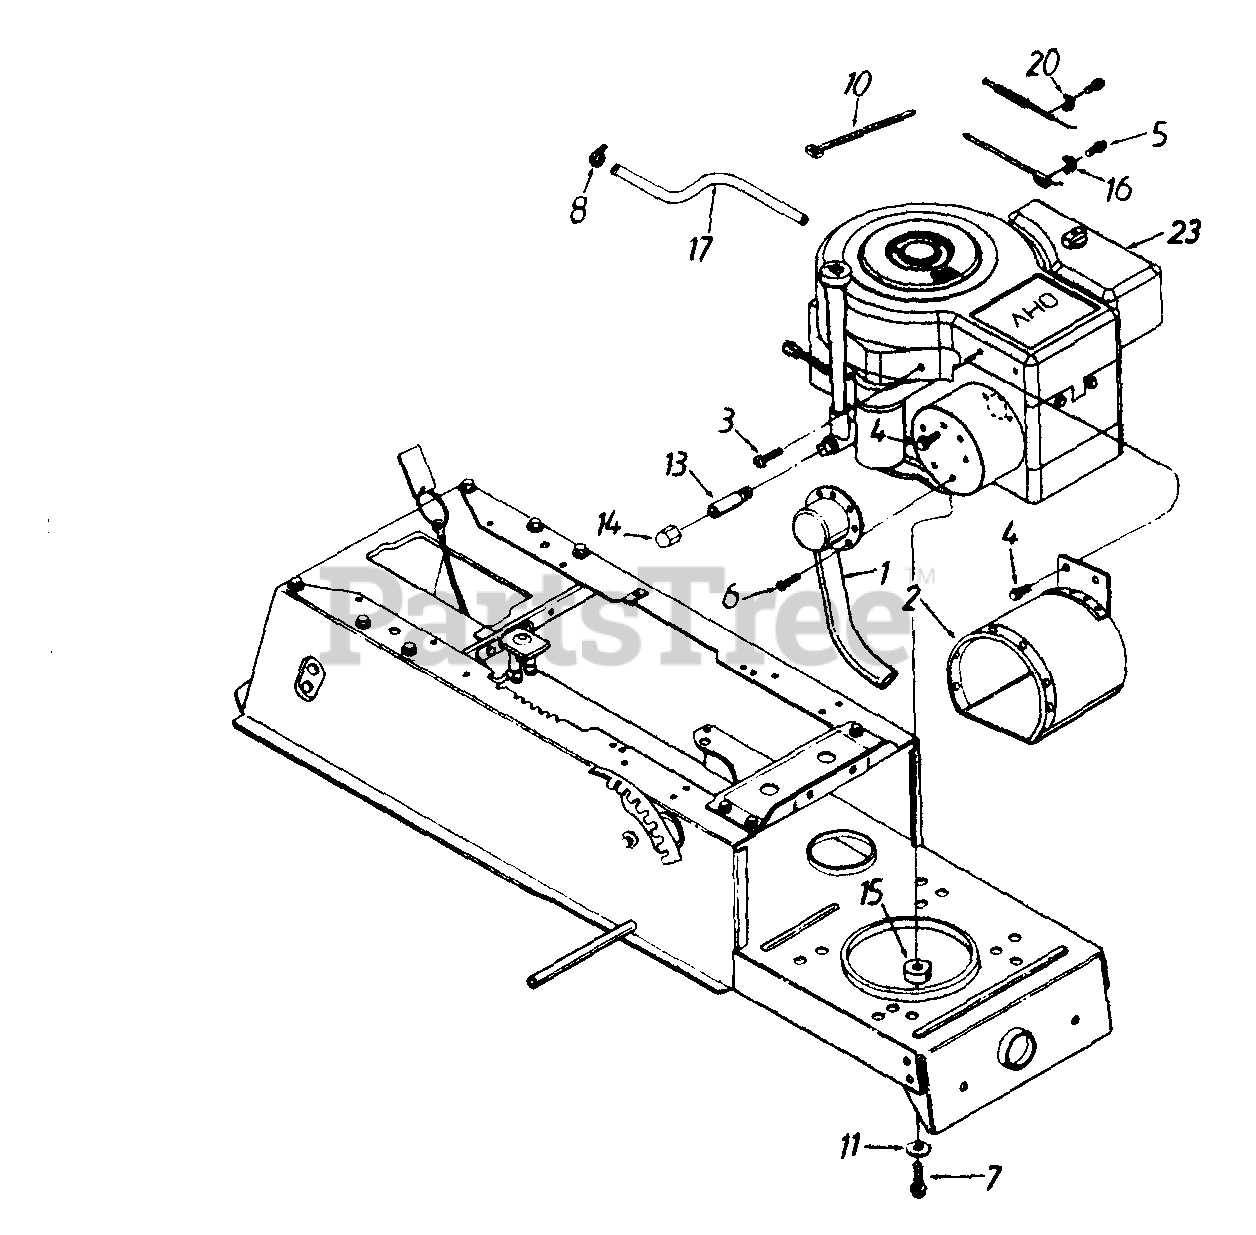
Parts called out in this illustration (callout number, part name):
1	Exhaust Pipe Ass'y.
2	Heat Shield Ass'y.
3	Pan Hd. Mach. Scr. 5/16-18 x .75"
4	Hex Wash. Hd. Scr. 1/4-20 x .5"
5	Hex Slot Wash. Hd. #10-32 x 5/8" Lg.
6	Hex Wash. Hd. F-Tap Scr. #8-32 x .38"
7	Hex L-Wash. TT-Tap Scr. 3/8-16 x 1.5"
8	Hose Clamp - .49" Dia.
10	Cable Tie - 4" I.D.
11	Flat Wash. 3/8" I.D. x 1.25" D.D.
13	Pipe Nipple 3/8-18 NPT x 2" Lg.
14	Cap - Oil Drain
15	Shld. Spacer .38" I.D. x 1.25" O.D.
16	Casing Clamp
17	Fuel Line Hose
20	Casing Clamp
23	Engine
